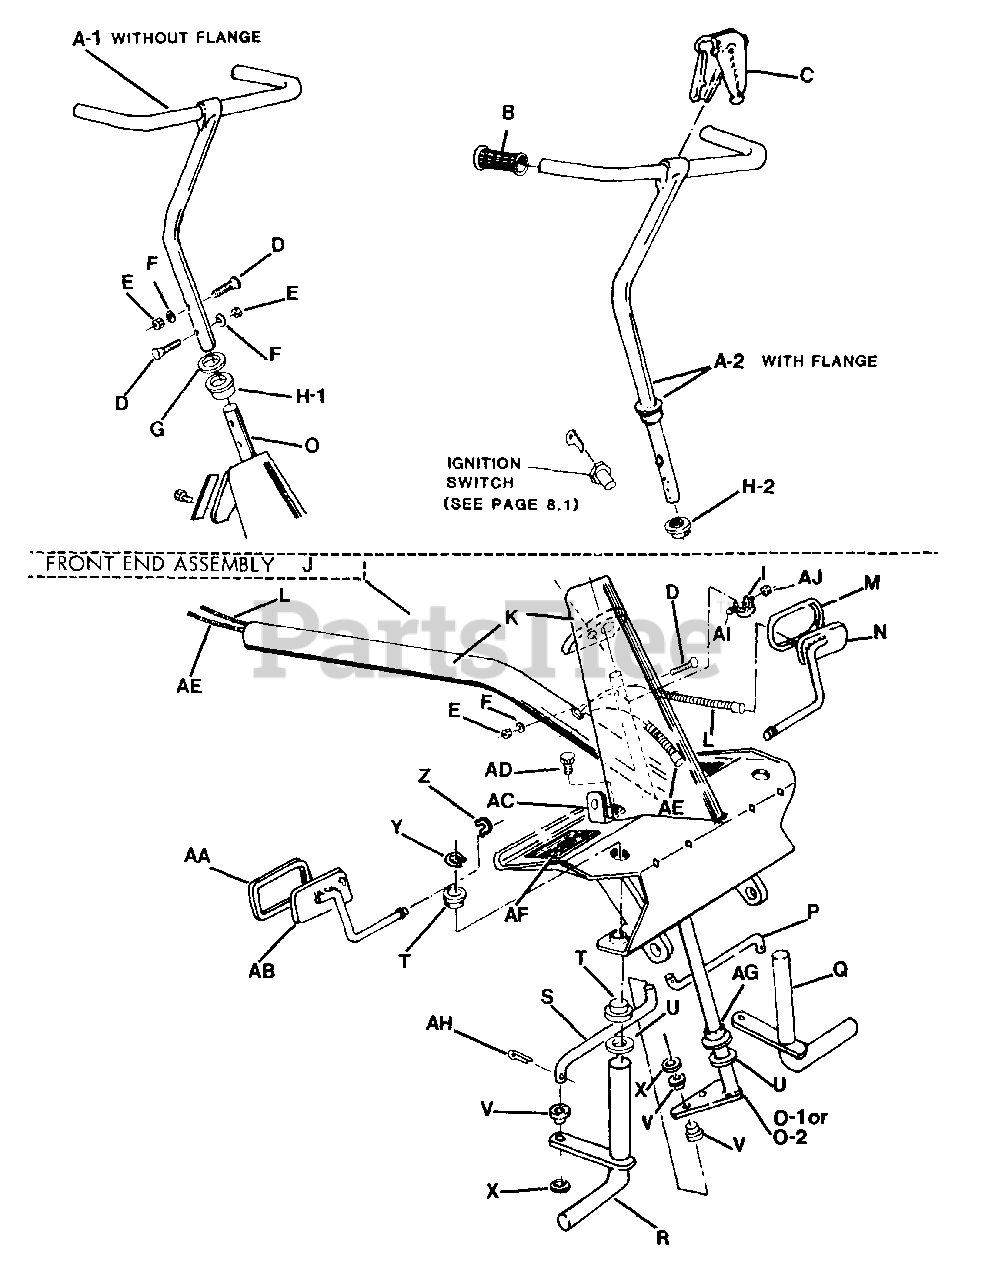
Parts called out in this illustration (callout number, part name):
A1	HANDLE, STEERING
A2	HANDLE, Steering
B	GRIP, STEERING HANDLE
C	COVER, HANDLE CENTER
D	BOLT, 1/4-28 TAPERED HEAD
E	NUT, 1/4-28 HEX
F	WASHER 1/4 INTERNAL TOOTH LOCK
G	WASHER, SHIM
H1	BUSHING, NYLON
H2	BUSHING, NYLON
I	CLAMP
J	FRONT END ASSEMBLY (No longer available)
K	WELD, FRONT AXLE (STD 25"-30" with plate for throttle)
K	WELD, FRONT AXLE (STD 25"-30" with plate for switch)
K	WELD, FRONT AXLE (Wide 33"-42" with plate for switch)
L	CABLE, CLUTCH / BRAKE (50.72" Yellow coded)
L	CABLE, CLUTCH / BRAKE (54.12" Black coded)
M	PAD, CLUTCH/BRAKE PEDAL (LH Side)
N	PEDAL, CLUTCH/BRAKE
O1	SHAFT, STEERING
O2	SHAFT, STEERING
P	TIE-ROD, Left Hand
P	TIE-ROD, LEFT HAND
Q	King Pin, L.H.
R	King Pin, R.H.
S	TIE-ROD, Right Hand
S	TIE-ROD, RIGHT HAND
T	BEARING
U	WASHER
V	BEARING
X	WASHER, 3/8 SAE
Y	RING, RETAINING
Z	RING, RETAINING
AA	PAD, AUX. BRAKE PEDAL
AB	PEDAL, AUX. BRAKE (RH Side)
AC	MOUNT, AUX. BRAKE PEDAL
AD	SCREW, SELF-TAPPING 5/16-18 x 5/8
AE	CABLE, AUX. BRAKE (41.625" Orange coded)
AE	CABLE, AUX. BRAKE (45.0" Red coded)
AF	PAD, Foot
AG	BUSHING, NYLON
AH	COTTER-PIN, 1/8 x 3/4
AI	BOLT, 5/16-18 x 1-1/2 CARRIAGE
AJ	NUT, 5/16-18 HEX
